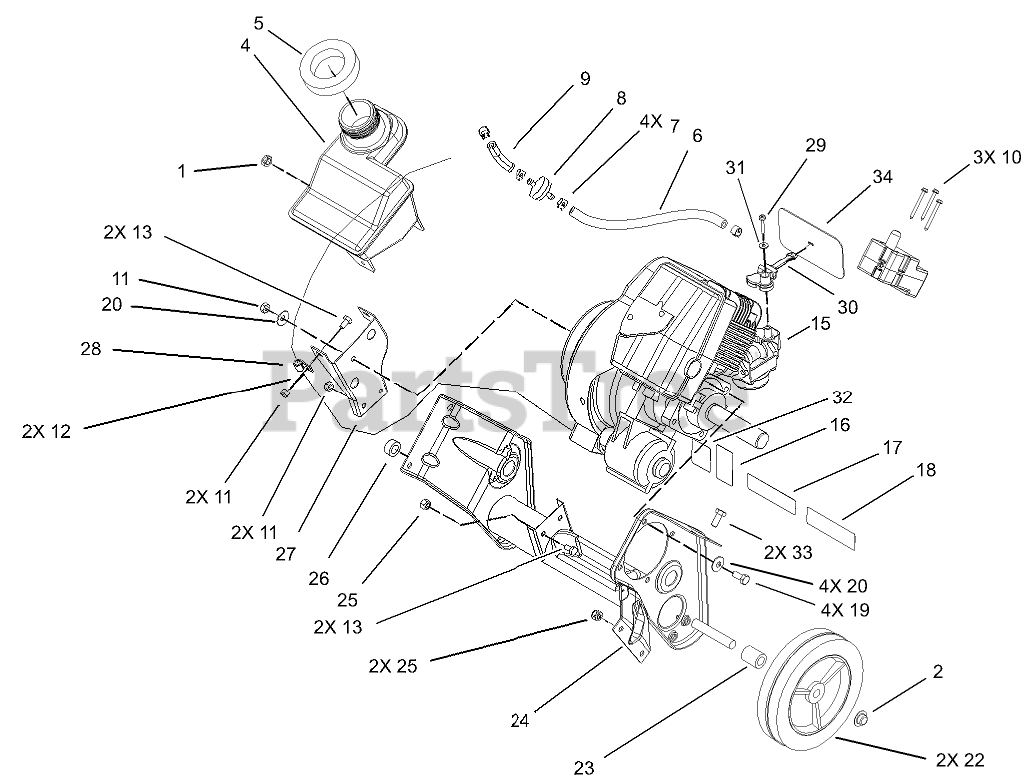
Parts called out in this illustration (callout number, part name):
1	NUT-LOCK, CONE
4	Tank-Gas
5	SEAL-FOAM
6	LINE-FUEL
7	CLAMP-HOSE
8	FILTER-FUEL
9	HOSE-FUEL
10	SCREW-PLASTITE
11	NUT-LOCK, NI
12	WASHER-FLAT
13	SCREW-HH
19	SCREW-HH
20	WASHER-BELLEVILLE
21	NUT-PUSH
22	WHEEL
23	SPACER-WHEEL
25	NUT-LOCK, NI
26	SPACER-WHEEL
27	BRACKET-SUPPORT, RECOIL
28	CLAMP
29	SCREW-PPH, PLASTITE
30	LEVER-CHOKE
31	WASHER-FLAT
33	SCREW-HH
34	SHIELD-HOLE, CHOKE
